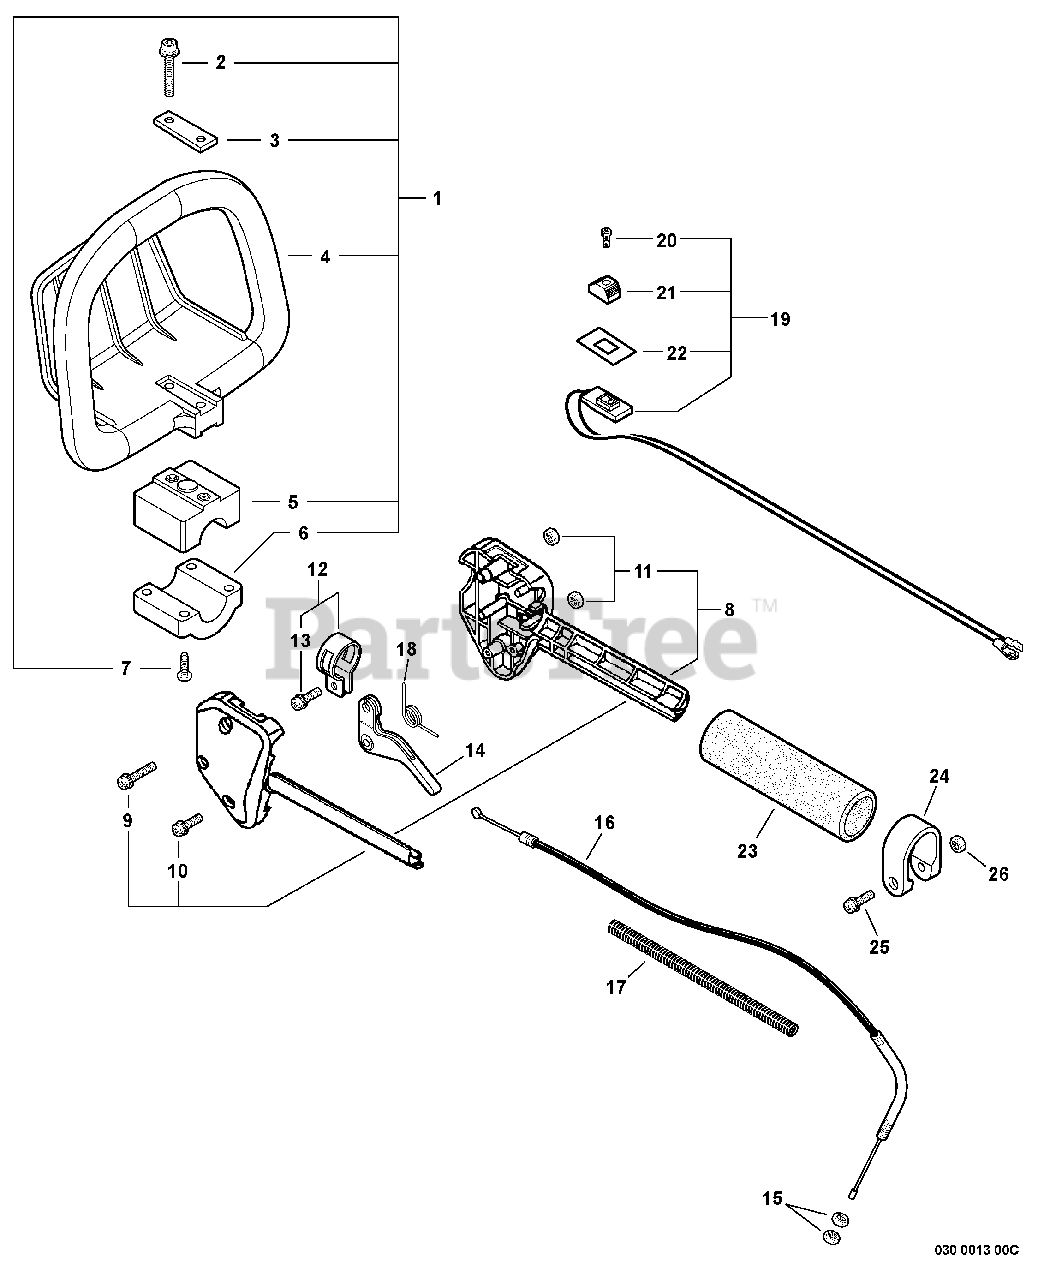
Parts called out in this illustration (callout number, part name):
1	HANDLE ASSY - FRONT
2	SCREW - 5X30
4	HANDLE - FRONT
5	BRACKET, HANDLE - UPPER
6	BRACKET, HANDLE - LOWER
7	SCREW - 5
8	CONTROL HANDLE ASSY
9	SCREW - 5X35
10	SCREW - 5X25
12	CLAMP KIT
13	SCREW - 5X14
14	TRIGGER, THROTTLE
16	CABLE, THROTTLE
17	TUBE, PROTECTIVE - CORRUGATED
18	SPRING, TRIGGER
19	IGNITION SWITCH ASSY
20	SCREW - 3X10
21	KNOB, SWITCH - ORANGE
22	COVER, SWITCH - STOP
23	GRIP, HANDLE - REAR
25	SCREW - 5X28
